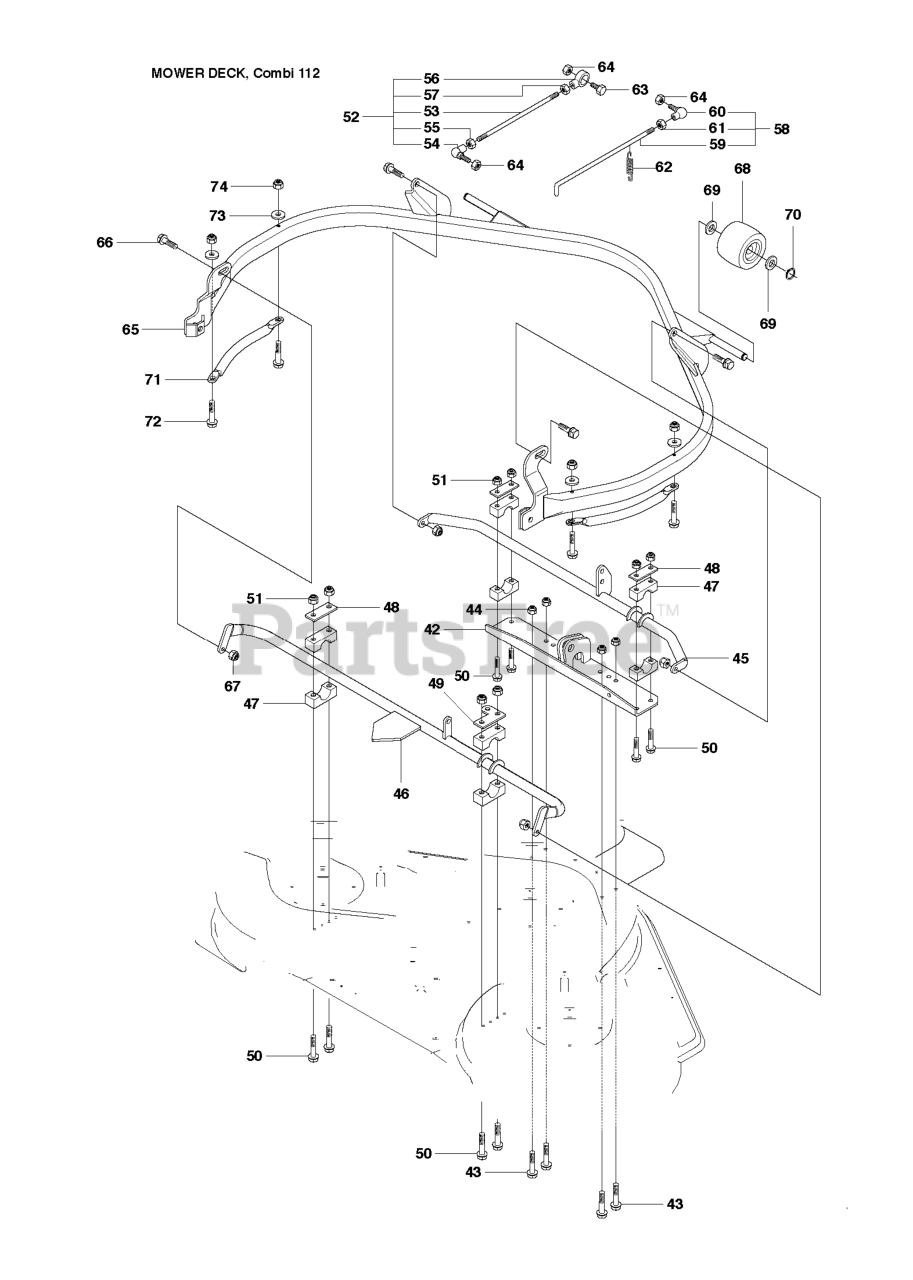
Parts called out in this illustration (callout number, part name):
44	LOCKNUT M8
51	LOCKNUT M8
52	PARALLEL RODY ASSY
57	NUT
58	CLUTCH ROD ASSY
64	NUT
67	LOCKNUT M8
68	DECK ROLLER, FRONT
70	RETAINING RING SGA 15
73	WASHER
74	LOCKNUT M6
